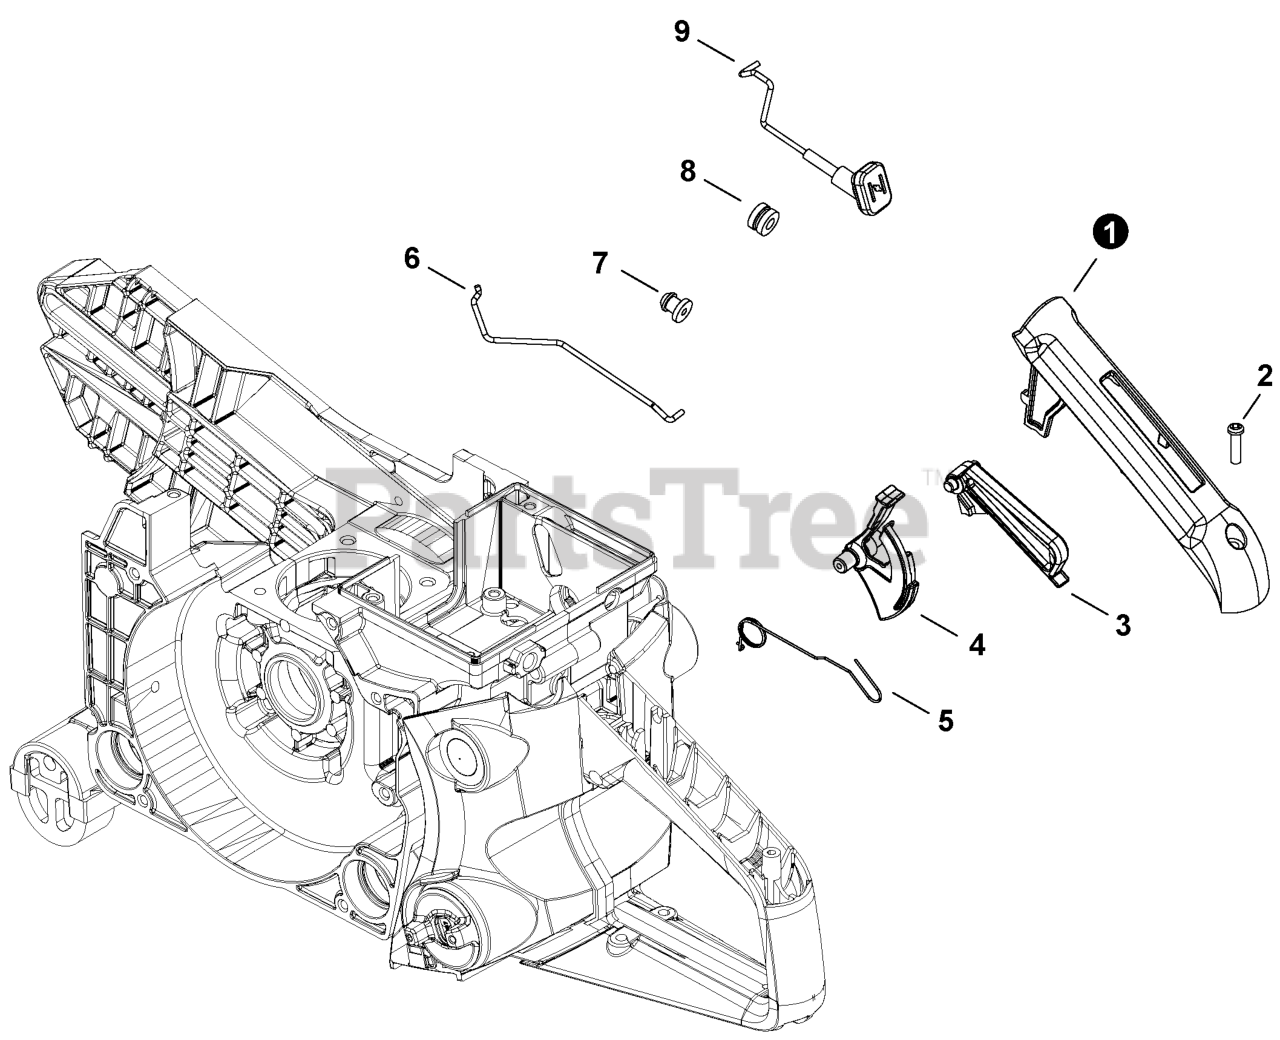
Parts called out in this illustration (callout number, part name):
1	COVER, HANDLE
2	SCREW 4
3	LEVER, THROTTLE LOCKOUT
4	TRIGGER, THROTTLE
5	SPRING, TORSION
6	ROD, THROTTLE
7	GROMMET
8	GROMMET, CHOKE
9	ROD, CHOKE
